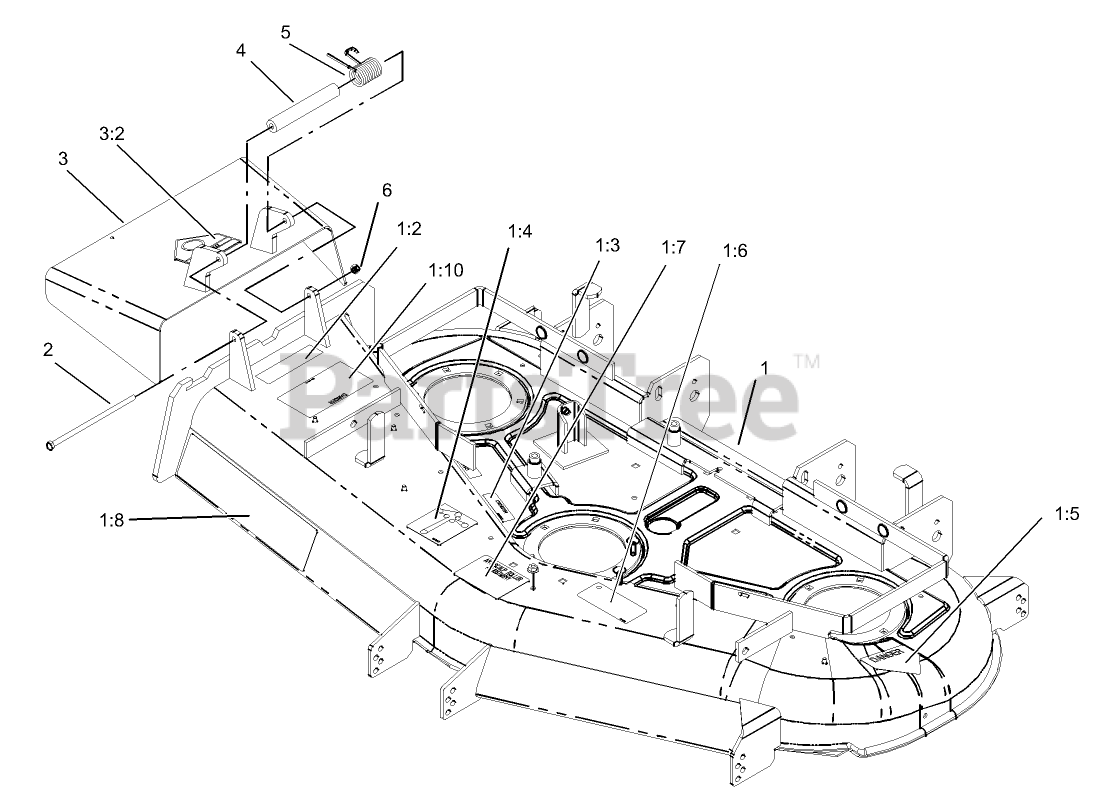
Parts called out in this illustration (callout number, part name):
1	Deck ASM
1:2	DECAL-WARNING
1:3	DECAL-COVER, MISSING
1:4	DECAL-ROUTING, BELT
1:5	DECAL-DANGER
1:6	DECAL-TORQUE, BLADE BOLT
1:7	DECAL-WHEEL, GAGE
1:8	DECAL
1:10	DECAL-DANGER, THROWN OBJECT
2	SCREW-HH
3	Deflector ASM
3:2	DECAL-DANGER
4	SPACER
5	SPRING-TORSION
6	NUT-LOCK, NI
